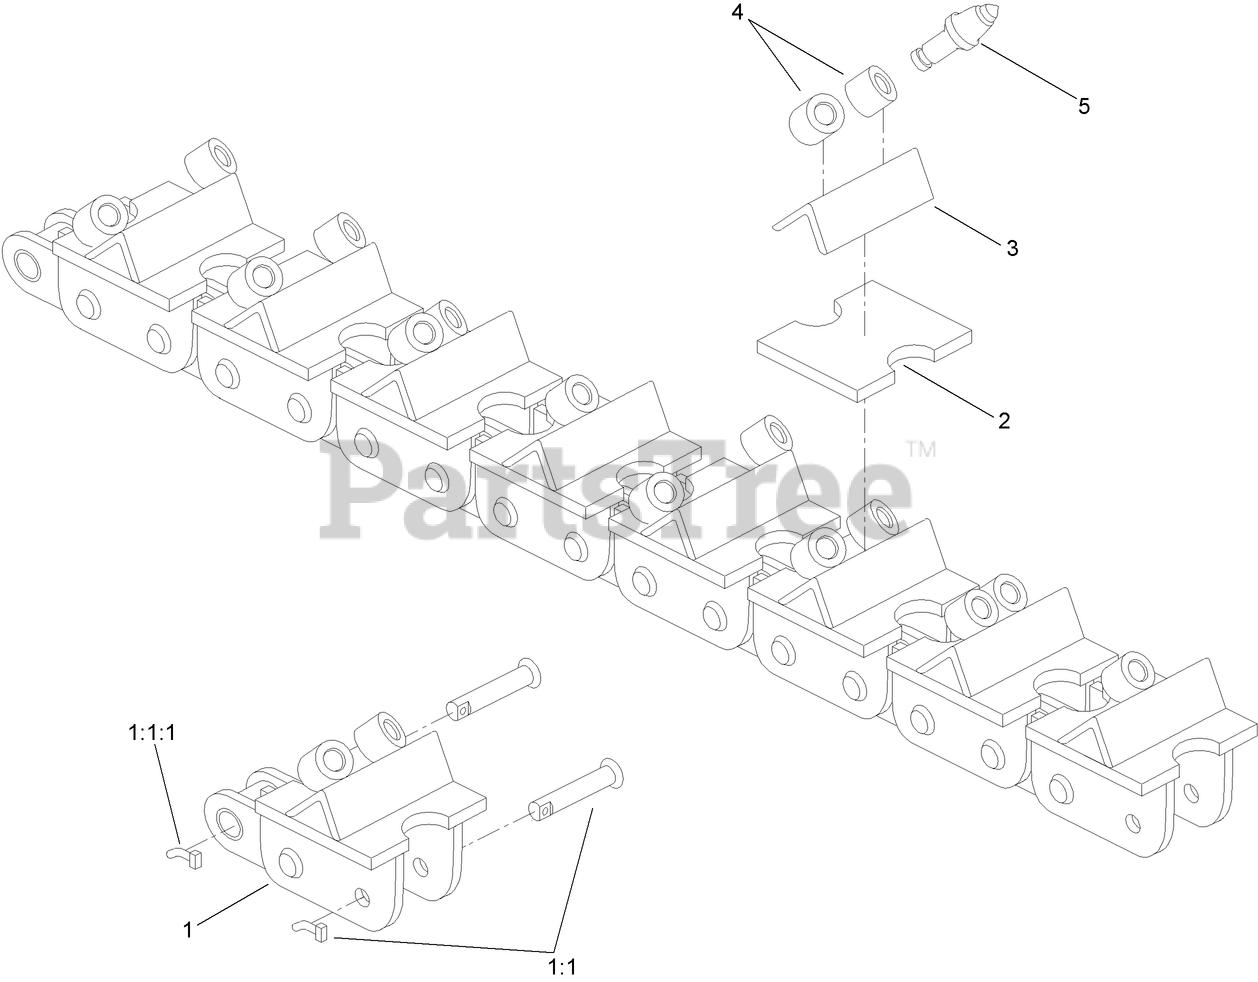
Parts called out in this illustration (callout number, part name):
1	CHAIN REPAIR LINK ASM
1:1	NOTCHED PIN AND KEEPER ASM
1:1:1	PIN-KEEPER
2	PLATE-H, WELD-ON
3	ANGLE-4 INCH
4	HOLDER-BIT
5	BIT-RETAINER, REAR
